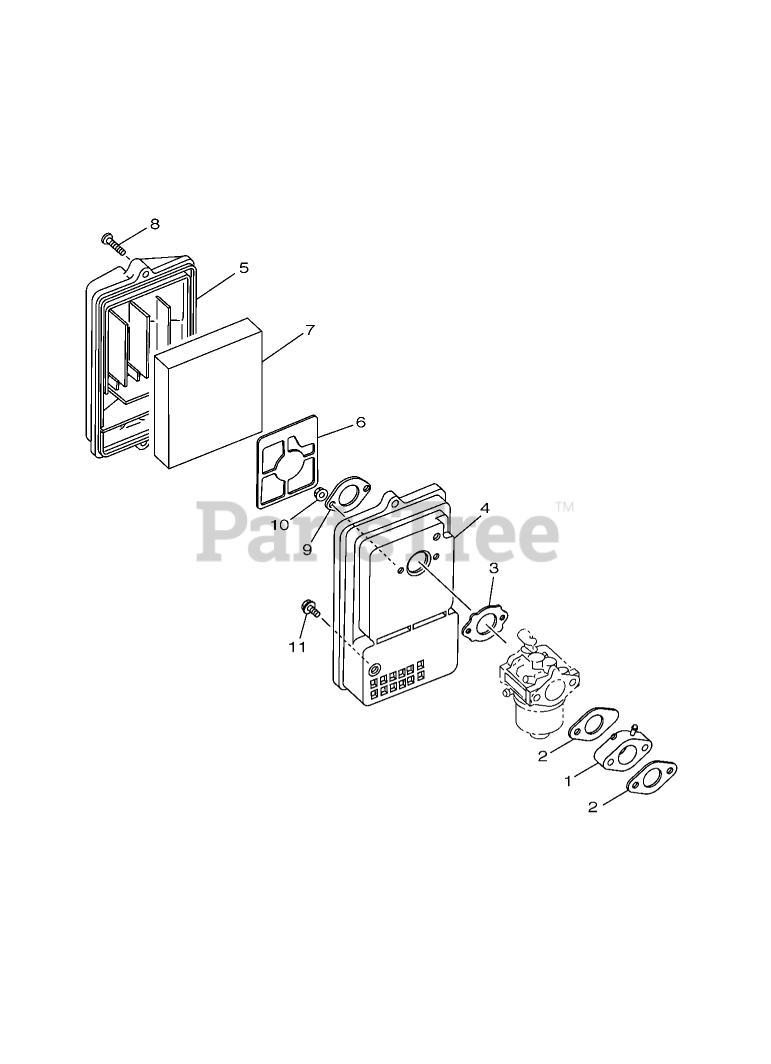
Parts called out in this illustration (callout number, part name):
1	MANIFOLD, INTAKE
2	GASKET, INTAKE
3	GASKET, A/C
5	COVER,A/C
7	ELEMENT, FOAM
10	NUT A/C H-D
11	SCREW, HEX FLANGE
